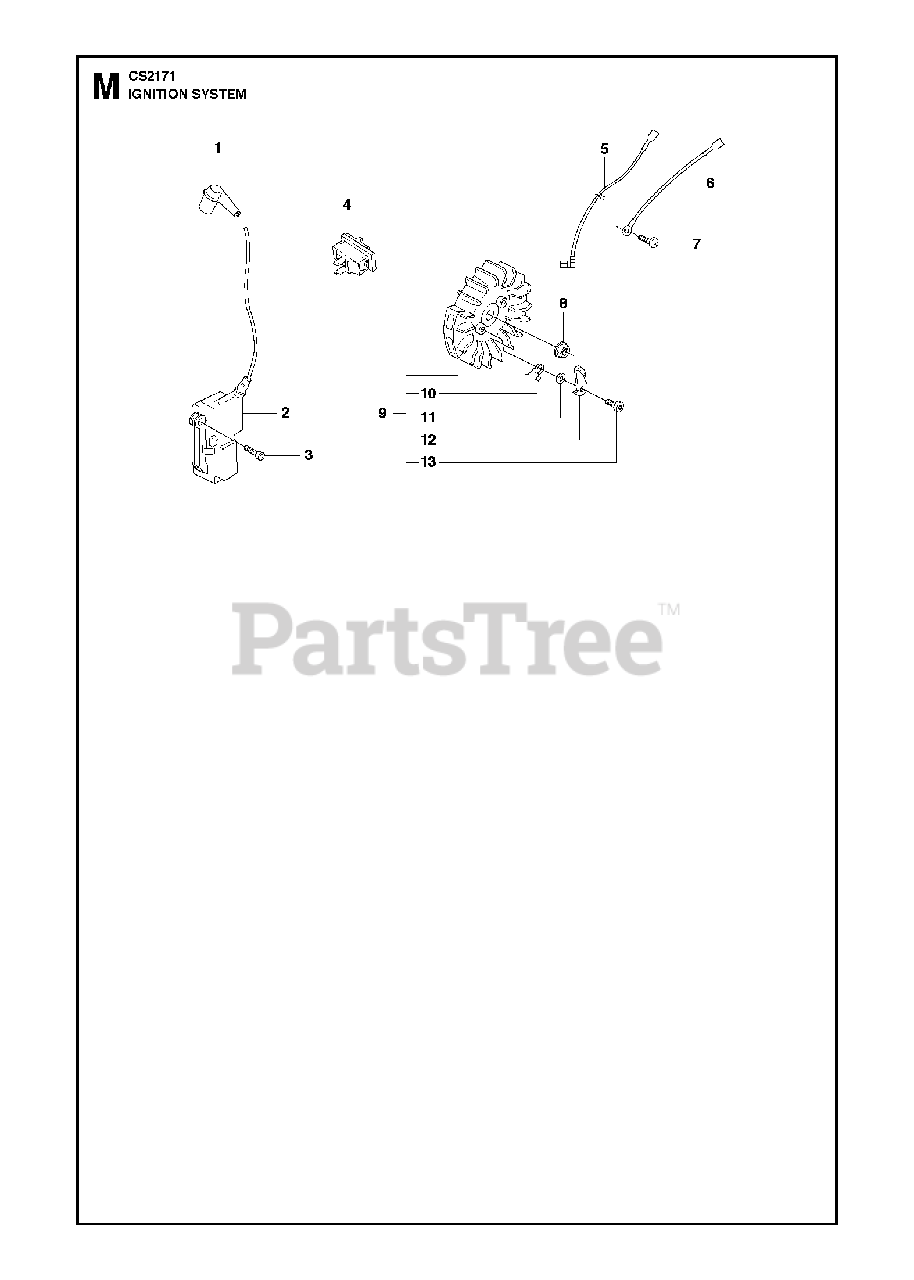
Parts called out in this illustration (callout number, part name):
1	SPARK PLUG CONN. KIT
2	IGNITION MODULE
4	START/STOP SWITCH
8	NUT W/ WASHER
10	SPRING
11	WASHER
12	PAWL
13	SCREW M5X14
